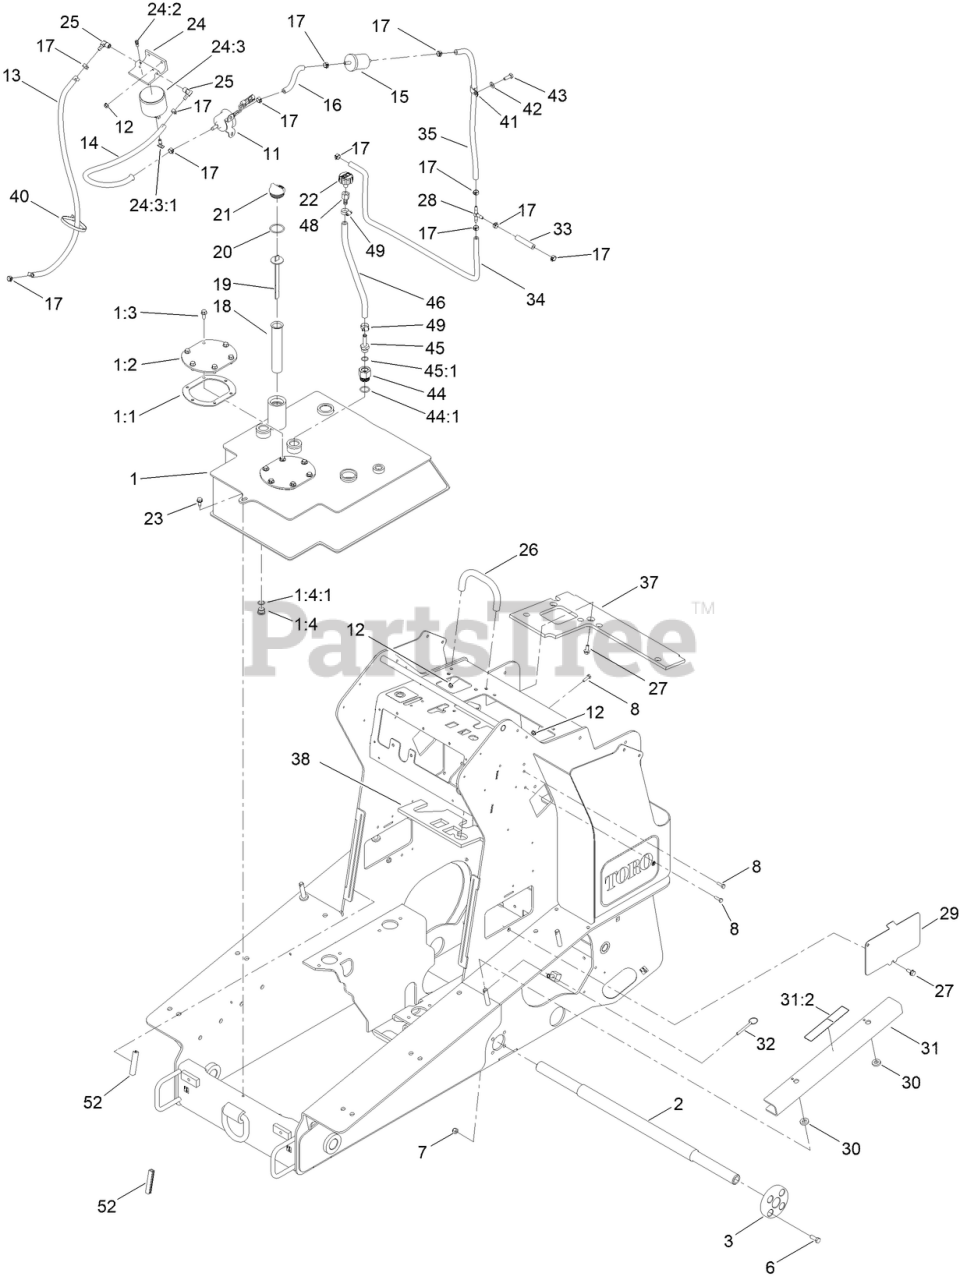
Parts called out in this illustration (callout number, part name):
1	TANK-HYD
1:1	GASKET-COVER, ACCESS
1:2	COVER-TANK
1:3	SCREW-HHF
1:4	PLUG-HEX
1:4:1	O-RING
2	SHAFT-TRACK
3	HUB-SHAFT
6	SCREW-HH
7	NUT-LOCK, NI
8	SCREW-HH
11	PUMP-FUEL, ELECTRIC
12	NUT-HF
13	HOSE-FUEL
14	HOSE-FUEL
15	FILTER-FUEL
16	HOSE-FUEL
17	CLAMP-HOSE
18	FILTER-SCREEN
19	DIPSTICK
20	O-RING
21	PLUG-PLASTIC
22	BREATHER
23	SCREW-THD ROLL, HWH
24	FILTER HEAD ASM
24:2	VENT-AIR
24:3	ELEMENT-SPIN ON
24:3:1	VALVE-DRAIN
25	FITTING-HYD, 90
26	BAR-REFERENCE
27	SCREW-HHF
28	FITTING-TEE, BARBED
29	PLATE-COVER, ACCESS
30	WASHER-NEOPRENE
31	ARM-LOCKING
31:2	DECAL-DANGER
32	PIN-COTTERLESS
33	HOSE-FUEL
34	HOSE-FUEL
35	HOSE-FUEL
37	FOAM-HEAT SHIELD
38	FOAM-HEAT SHIELD
40	TIE-CABLE
41	CLAMP-R
42	WASHER-FLAT
43	SCREW-HH
44	FITTING-STRAIGHT
44:1	O-RING
45	FITTING-STR
45:1	O-RING
48	FITTING-FEMALE, BARBED
49	CLAMP-HOSE
